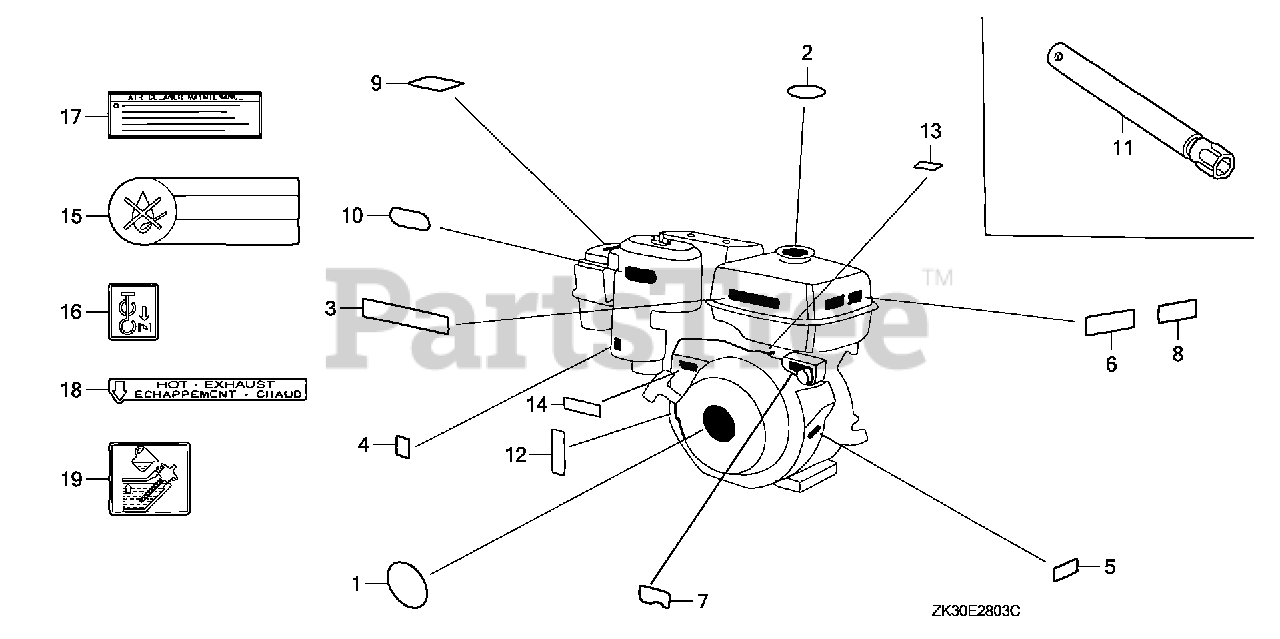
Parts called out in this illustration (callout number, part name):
1	EMBLEM (11. (HONDA)
2	MARK, CAUTION
3	LABEL, CAUTION (ENGLISH, ETC.)
4	MARK, CHOKE (ORANGE)
5	LABEL, SPECIFICATION (EXTERNAL) (NOT AVAILABLE)
6	MARK, OIL ALERT (GERMAN)
6	MARK, OIL ALERT (FRENCH)
8	MARK, OIL ALERT (ENGLISH)
11	WRENCH, SPARK PLUG
13	LABEL, FUEL CAUTION
